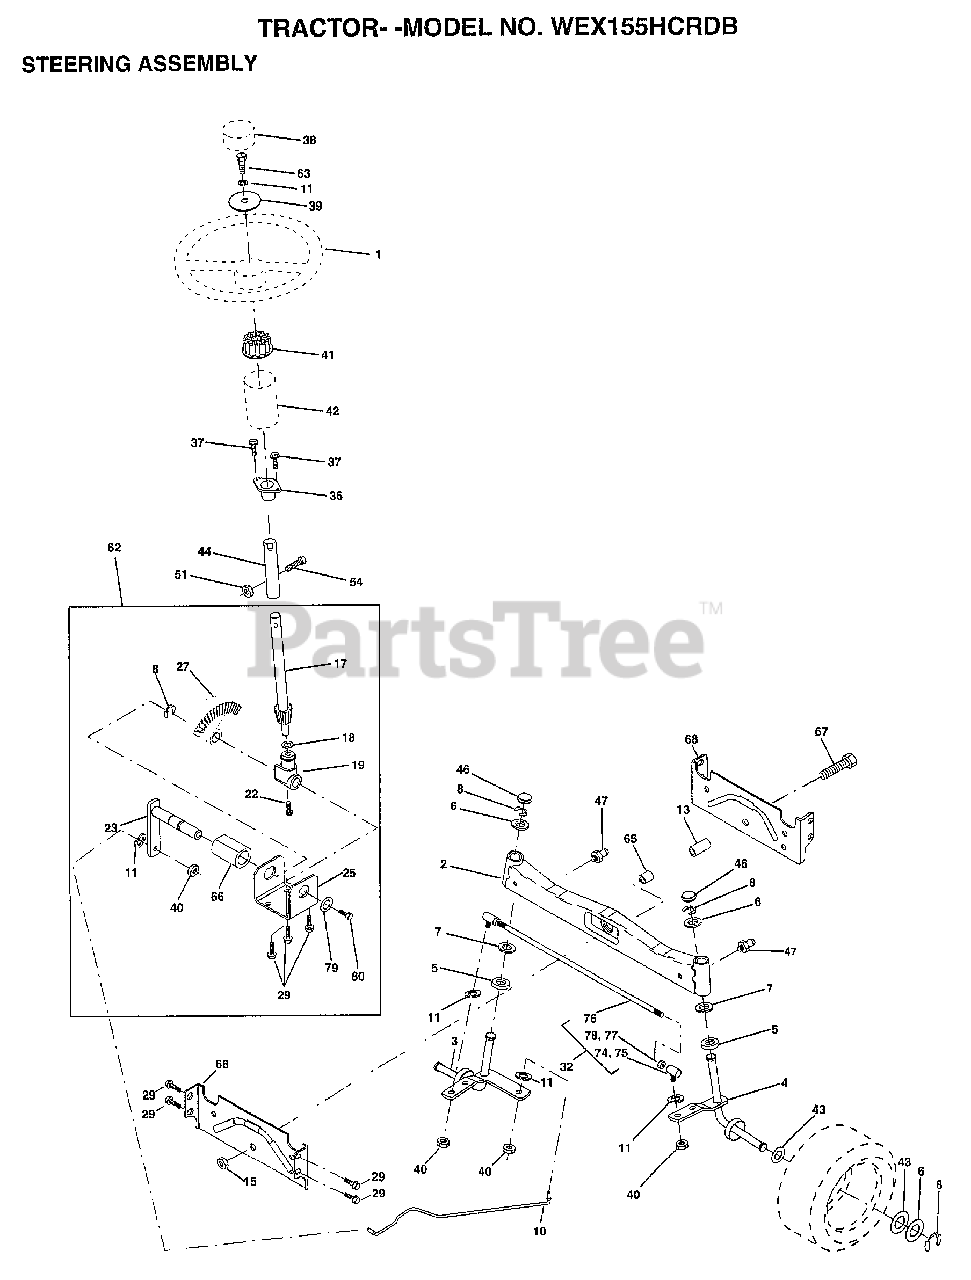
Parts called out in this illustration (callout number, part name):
1	WHEEL STR AYP BLK
3	"SPINDLE ASM,LH"
4	"SPINDLE ASM,RH"
5	WASHER .T
6	WASHER
7	WASHER
8	RING
10	LINK.DRAG
11	LOCKWASHER
13	BEARING.FRT.SPACER.AXLE
15	"NUT-LOC,FLANGE LT"
17	SHAFT ASM STEERIN
18	THRUST WASHER
19	SUPPORT.SHAFT.STEER
22	SCREW.HX.WSH.HD
23	SHAFT.ASM.PITMAN
25	BRKT-STEERING
27	GEAR SECTOR
29	SCREW
32	ROD.ASM.TIE.BALL
36	BUSHING.STEERING
37	"SCREW-TT,10-32 FL"
38	CAP STEER AYP
39	WASHER T
40	GRIPCO NUT
41	ADAPTER LT
42	BOOT.STEER.PL
43	WASHER
44	EXT SHAFT STEERIN
46	CAP
47	ZERK M
51	NUT
54	BOLT
62	KIT.STEER.ASM
63	BOLT
65	SPACER AXLE
66	"BEARING-ARM,PITMA"
67	BOLT
68	BRACE AXLE
74	JOINT.RH
75	JOINT.LH
77	NUT
78	NUT
79	WASHER
80	BOLT.HX.NYLON3/8-16X3/
